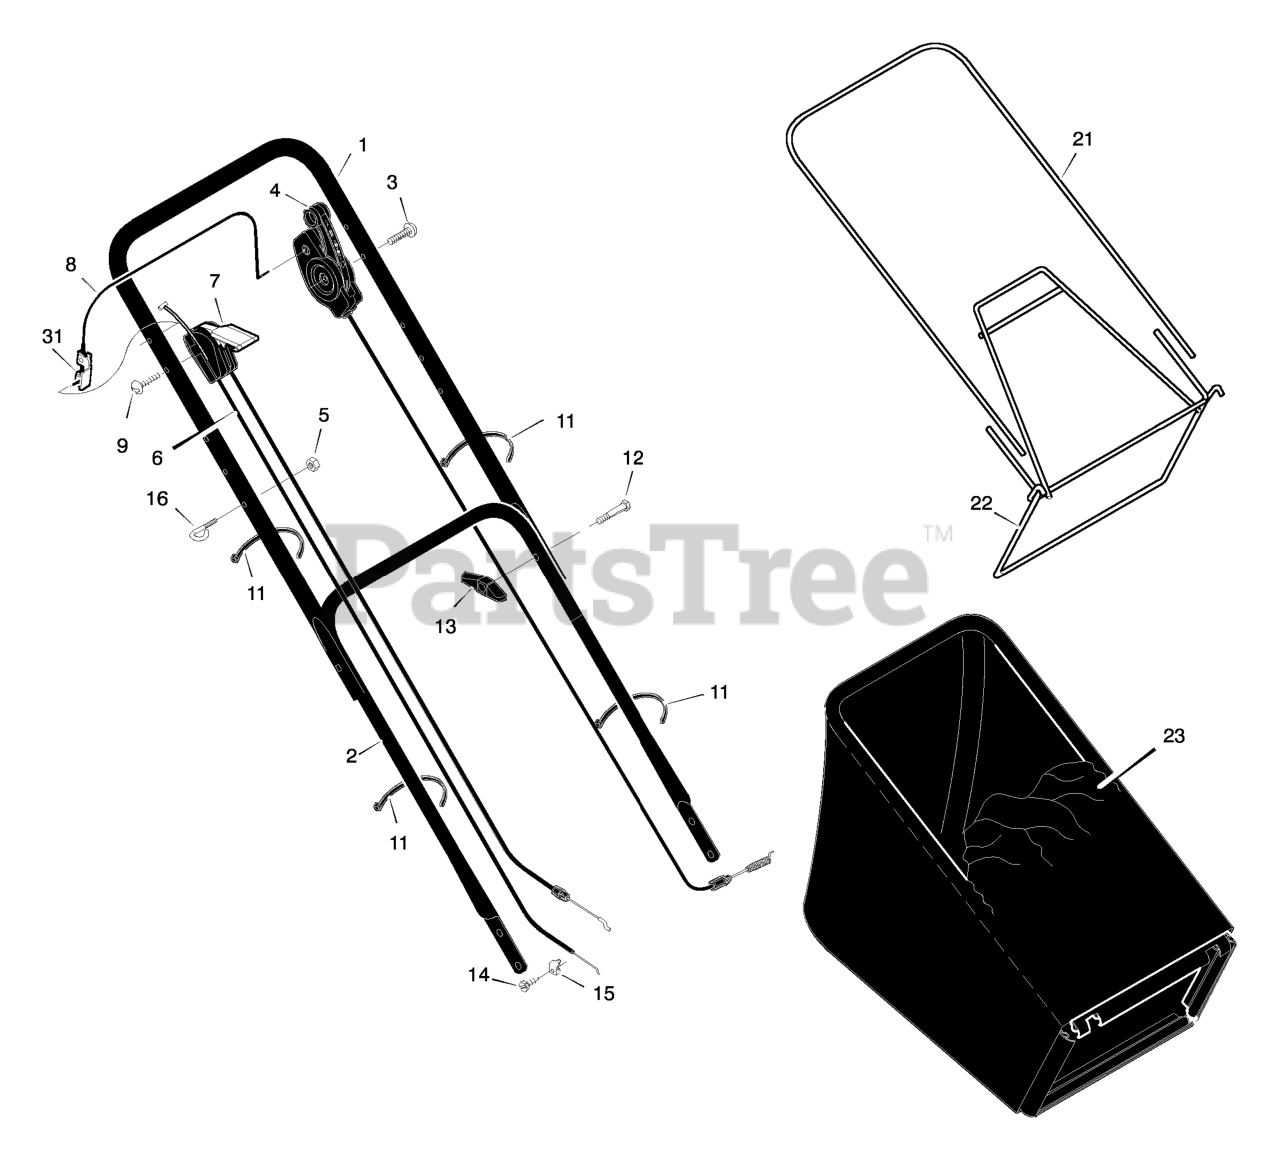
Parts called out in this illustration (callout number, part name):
1	Handle, Upper
2	Handle, Lower
4	Control, Drive
5	Locknut
6	Cable, Stop
7	Throttle Control
8	Engine Stop Lever
11	Fastener, Cable
13	Knob
16	GUIDE, ROPE
21	Frame, Top
22	Frame Assembly
23	Bag, Cloth
31	Bracket, Stop Lever
